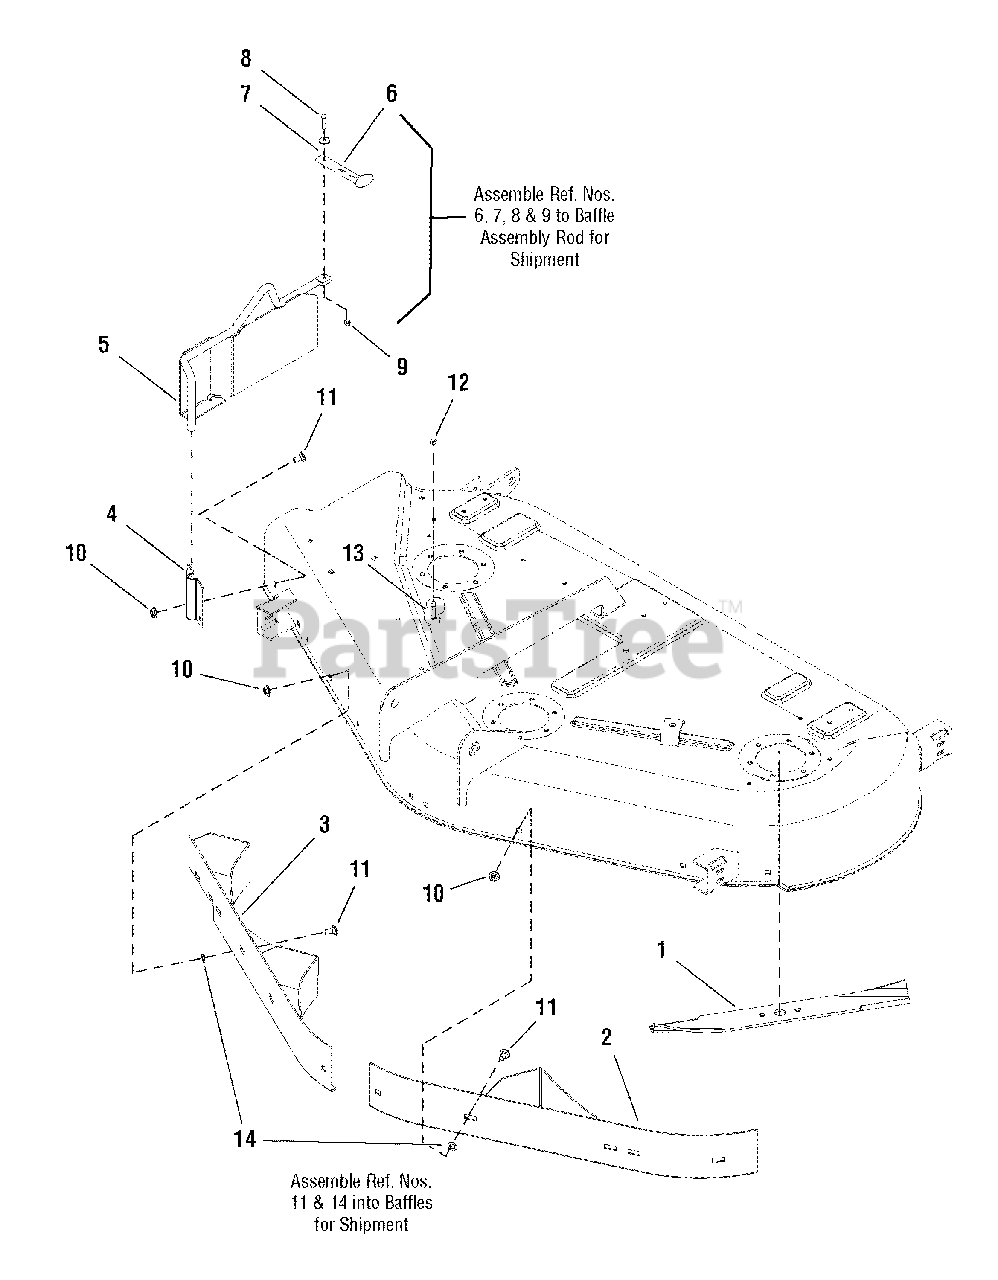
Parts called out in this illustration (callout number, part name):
1	BLADE, Mower, 50"
1	BLADE, Mower, 44"
2	BAFFLE & DEFLECTOR ASSEMBLY, L.H. 50"
2	BAFFLE & DEFLECTOR ASSEMBLY, L.H. 44"
3	BAFFLE & DEFLECTOR ASSEMBLY, R.H. 50"
3	BAFFLE & DEFLECTOR ASSEMBLY, R.H. 44"
4	PLATE, Chute Rod
5	BAFFLE ASSEMBLY, Mulcher 50"
5	BAFFLE ASSEMBLY, Mulcher 44"
7	WASHER, Flat, 3/16
8	SCREW, Phillips, Pan Head, #10-24 x 1
9	NUT, ESNA, 10-24
10	NUT, Whiz Lock, 5/16-18
11	BOLT, Carriage, 5/16-18 x 3/4
12	NUT, ESNA, 1/4-20
13	BOLT, Carriage, 1/4-20 x 1-1/2
14	NUT, PUSH, 5/16
